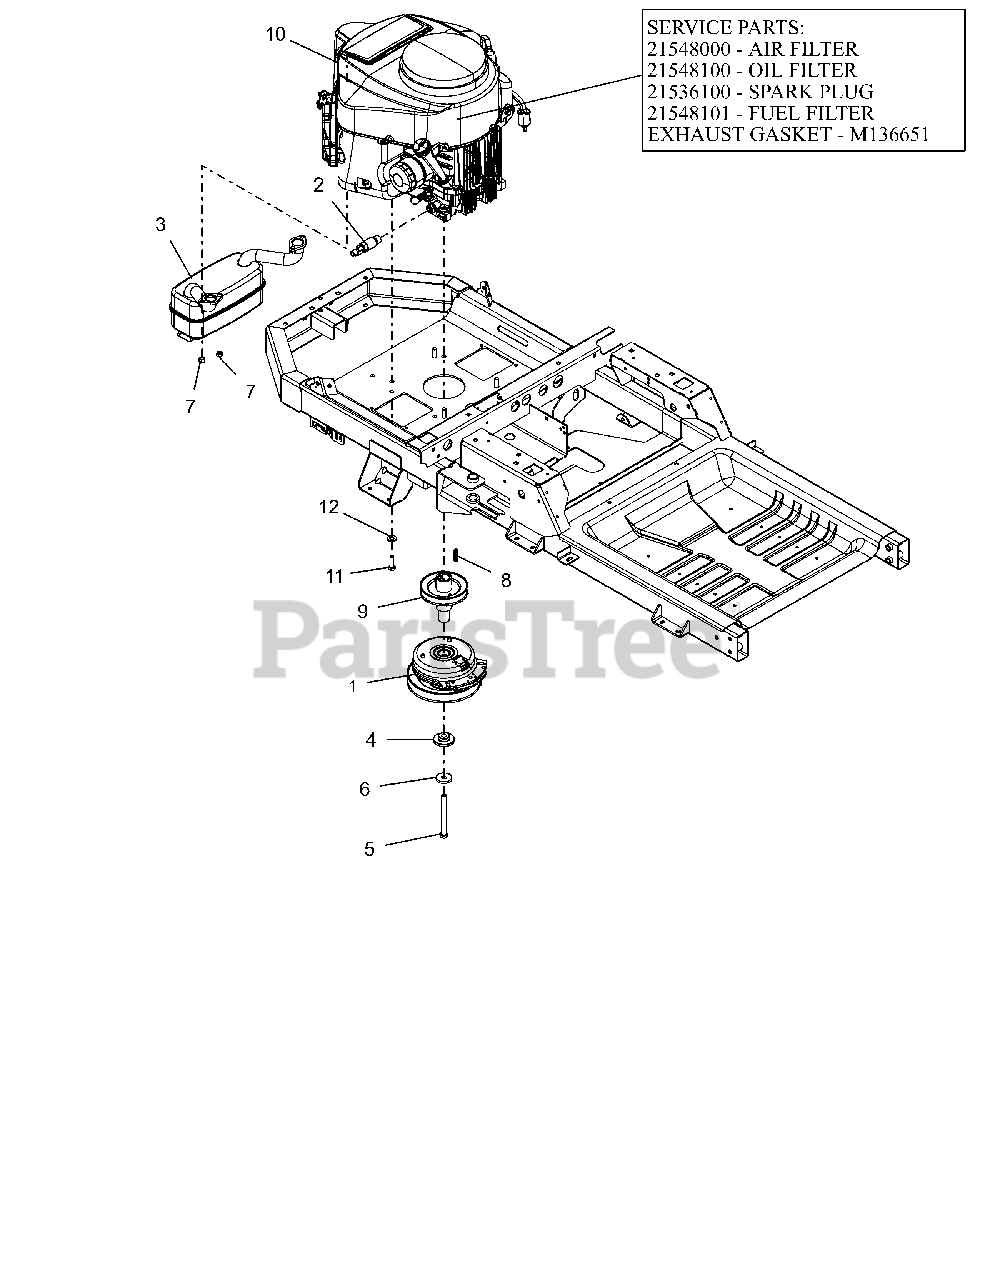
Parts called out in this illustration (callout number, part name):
1	CLUTCH,105FTLB MONOPOLE 6.83"
2	DRAIN, OIL M20X2.5
3	MUFFLER, KAWASAKI
4	BSHG-FLG .469X1.06X.574X2.0
5	BLT-HEX.438-20X4.5GR8YZ NYTORQ
6	WASHER, 7/16" SPRING DISK
7	NUT-LK-TOP M8-1.25 YWZC
8	KEY-SQ .25 X 1.25 X .25 SAE
9	WLDMT, DRIVE SHEAVE-X
10	ENGINE, KAWASAKI FR691 23HP
10	AIR FILTER, KAWASAKI FR
10	OIL FILTER, KAWASAKI FR
10	PLUG, SPARK
10	FUEL FILTER-KAWASAKI FR
10	GASKET, MUFFLER #
11	BLT-HEX.38-16X1.25 G5YZ NYTORQ
12	WASHER, 3/8" SPRING DISC
